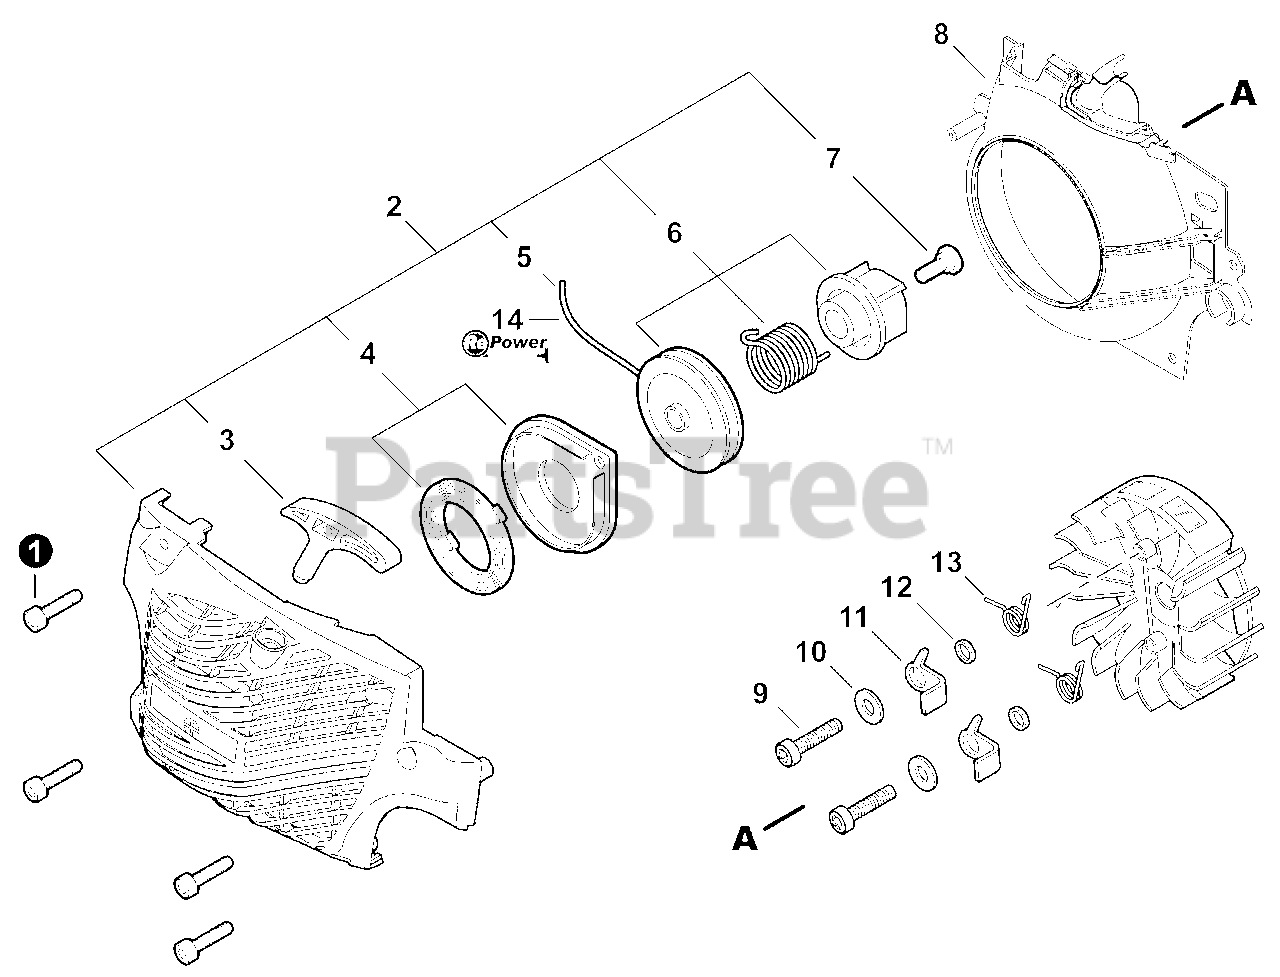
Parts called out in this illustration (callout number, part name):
1	BOLT, TORX 5×20
2	STARTER ASSY, RECOIL
3	GRIP, STARTER
4	SPRING KIT, RECOIL
5	ROPE, STARTER 3.5×900
6	REEL KIT, ROPE
7	SCREW
8	COVER, FAN
9	BOLT 5×14
10	WASHER 5.5×12×0.8
12	SPACER 5.2×8×2.1
13	SPRING, TORSION
14	ROPE, STARTER - REPOWER BULK
